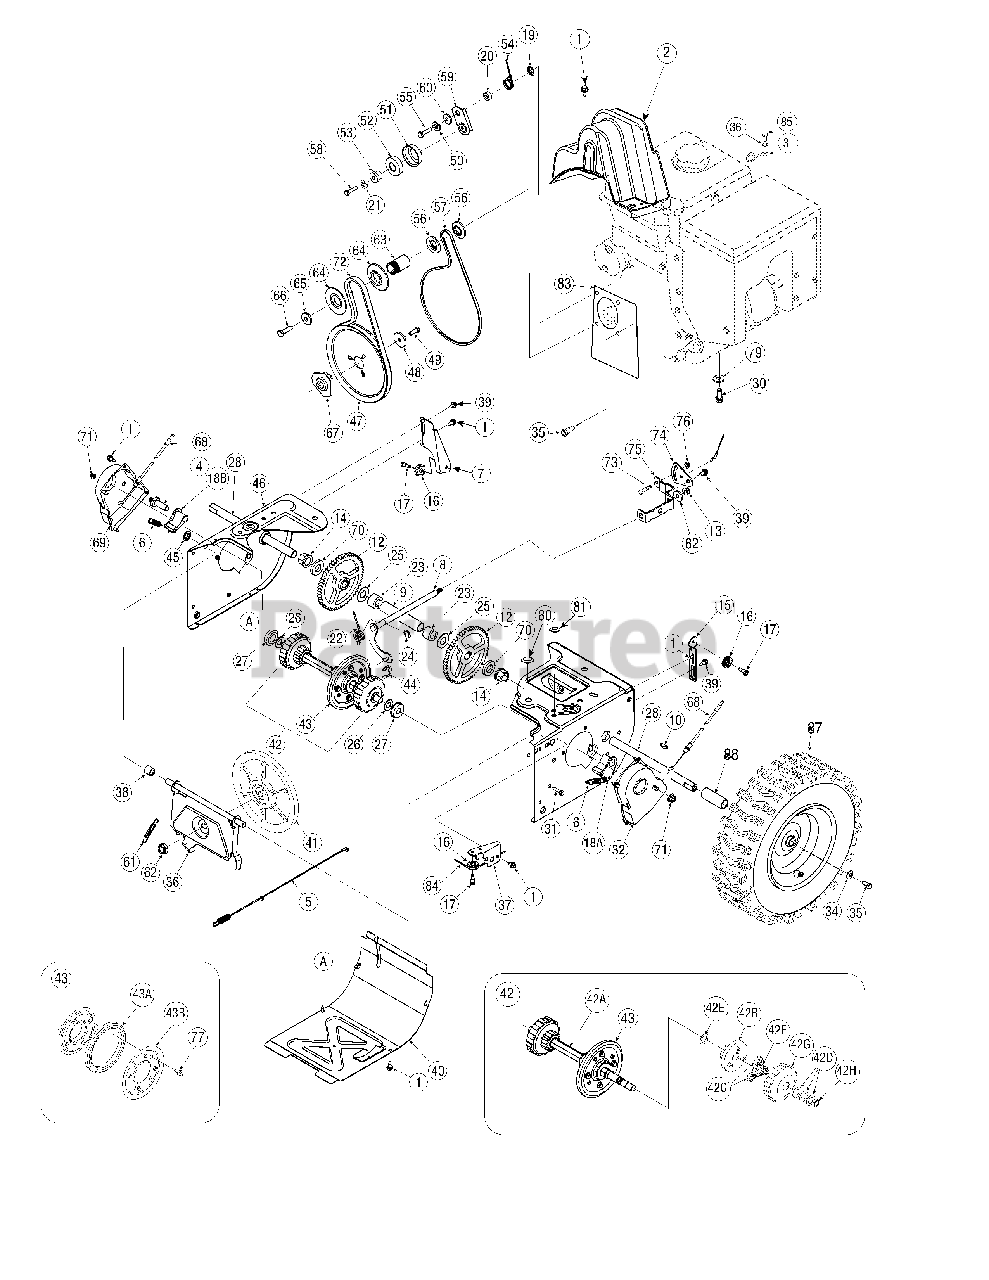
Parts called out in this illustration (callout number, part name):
1	Hex Wash Hd TT Scr. 1/4-20 x .625
2	Belt Cover (w/277 cc - 357 cc engines)
3	Cable Control Wire
4	Drive Shaft Actuator
5	Drive Clutch Cable 44.83" Lg.
6	Extension Spring .5 OD x 1.71 Lg.
7	Guide Bracket - Drive Cable
8	Shift Rod Ass’y
9	Axle Support Tube
10	#9 HI-Pro Key 3/16 x 3/4 Dia HT
13	Flange Lock-Nut 5/16-18 Gr. F Nylon
14	Hex. Flange Bearing.751" ID
15	Guide Bracket - Auger Cable
16	Cable Guide Roller
17	Hex Shld.Scr.1/4-28 x .375
18A	Dogg Assembly - LH
18B	Dogg Assembly - RH
19	Push Nut
20	Spacer .340 x .750 x .360" Lg.
21	L-Wash 1/4 ID
22	Torsion Spring .750 ID x .968" Lg.
24	Retaining Ring
25	Flat Washer .760 ID x 1.49 OD
26	Flat Washer .580 x 1.125 x .080
27	Ball Bearing
30	Hex Wash HD Tap Scr 3/8-16 x .88
31	Hex Bolt 1/4-20 x 1.00
34	Cupped Washer .345 ID x .88 OD x .060
35	Shoulder Screw .50 x .145: 5/16-24
37	Auger Cable Guide Bracket
38	Spacer .513 ID x 1.0
39	Shoulder Screw .373 x .105:TT 1/4-20
41	Friction Wheel Disc Assembly
42	Drive Shaft Assembly (w/o Friction Wheel Ass'y)
42A	Hex Drive Shaft (500)
42B	Planetary Carrier Ass'y
42D	Flat Washer .58 x 1.12 x .02
42E	Flat Washer 5/8 ID x 1.0 OD
42G	Ring Planetary Gear Ass'y (500)
42H	Retaining Ring 1.56 diam.
43	Friction Wheel Assembly
43A	Friction Wheel Rubber
43B	Friction Plate
44	Retainer Ring
45	Cap Speed Nut 1/4 Rod
47	Auger Pulley
48	Flat Washer .34 x 1.50 x .150
49	Hex Bolt 5/16-24 x 0.875
50	L-Wash 5/16 ID
51	Bearing Sleeve
52	Ball Bearing 20 x 47 x 14:6204:DS
54	Torsion Spring .850 ID x .354" Lg.
55	Hex HD. Cap Scr. 5/16-24 x 1.25 Lg.
56	Pulley Half
57	Belt 3/8 x 35.68" Lg.(w/277cc - 357cc engines)
58	Hex Bolt 1/4-20 x 1.25
59	Wheel Drive Idler Bracket
60	Shoulder Spacer
61	Extension Spring 3/8 OD x 2.50
62	Jam L-Nut 5/8-18 Gr. 5 Nylon
63	Spacer .875 ID x 1.185 OD
64	Pulley Half
65	Flat Washer .40 ID x 1.25 OD x .160
66	Hex Screw 3/8-24 x 1.25
67	Pulley Adapter
68	Steering Cable
70	Axle Spacer
71	Flange Lock-Nut 3/8-16 Gr. F Nylon
72	Belt .5 x 37.0 (w/277cc - 357cc engines)
73	Hex Bolt 1/4-20 x .62 Gr. 5
74	Pivot Bracket
75	Shift Bracket
76	Flange Lock-Nut 1/4-20 Gr. F Nylon
77	Hex Wash. Hd. TT Scr. 1/4-14 x .625
79	Flat Washer .38 x 1.38 x .125 (Rear left hole)
82	Flat Washer .469 x .875 x .105
83	Cover Plate (optional)
84	Auger Clutch Cable 47.23" Lg.
85	Hex. Hd. Cap Scr. M8-1.25:20 Gr. 8
86	Flat Washer .330 ID x .630 OD x .0635
88	Spacer, Wheel 1.25ODX.75X3.00
